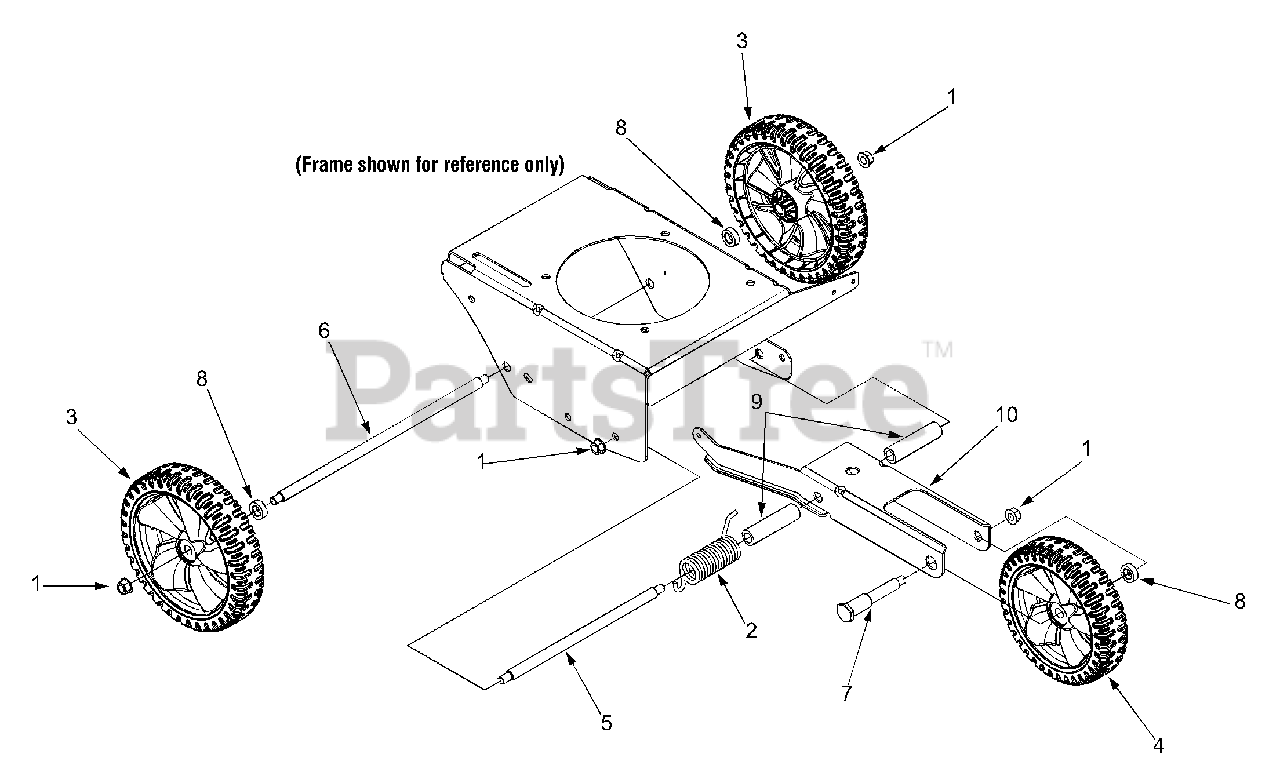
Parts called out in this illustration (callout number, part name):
1	Flange Lock Nut, 3/8-16
2	Torsion Spring
3	Wheel 8x1.8
4	Wheel 7x1.8
5	Shoulder Screw,.50 x 9.36, 3/8-16
6	Shoulder Screw,.50 x 12.90, 3/8-16
7	Shoulder Screw,.50 x 3.19, 3/8-16
8	Spacer,.510 ID x.875 OD
9	Spacer,.525 x.775
